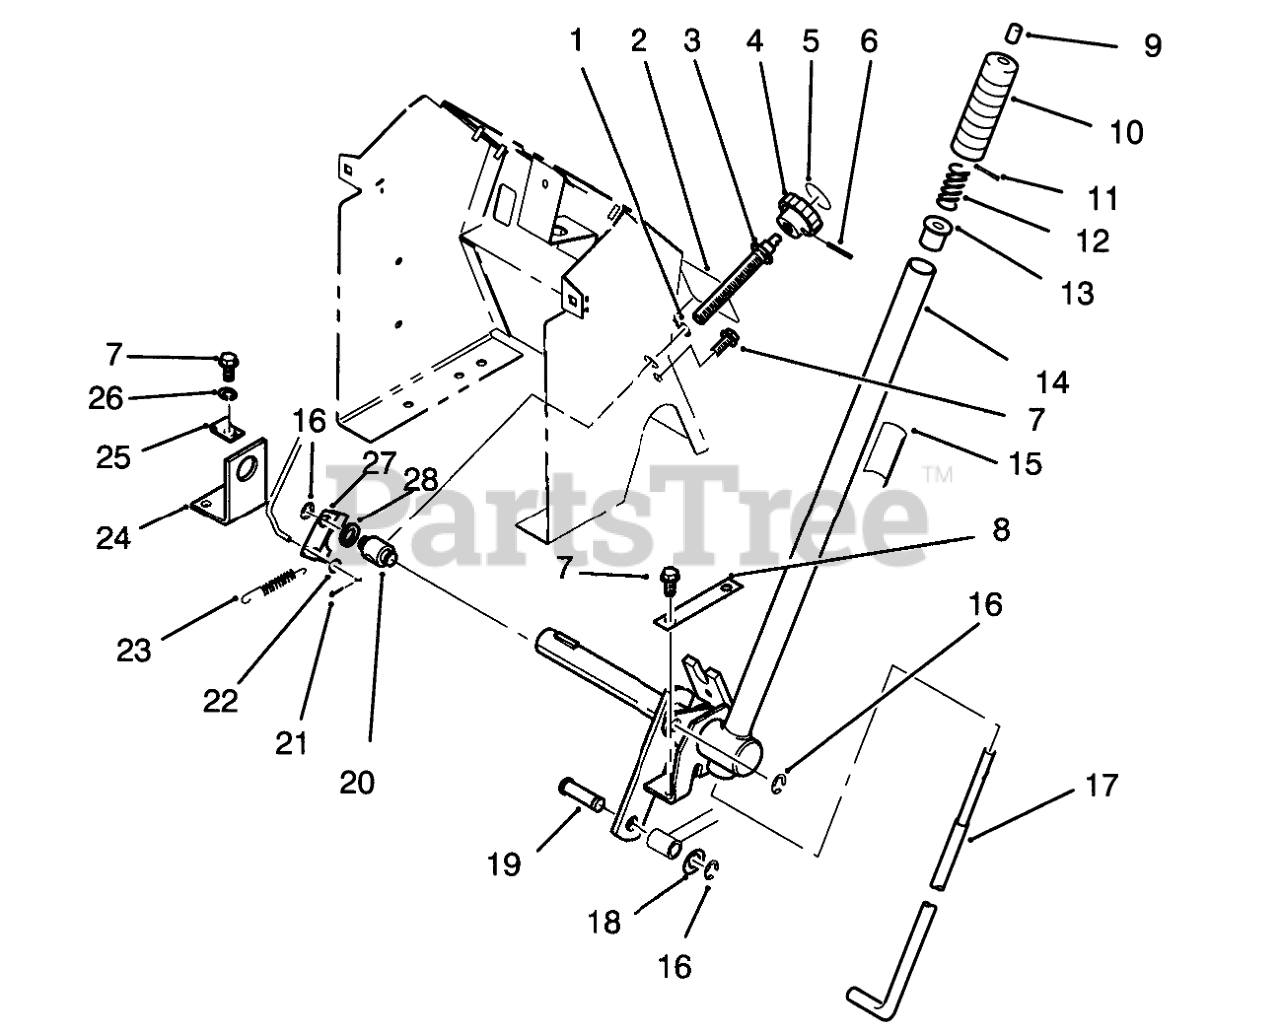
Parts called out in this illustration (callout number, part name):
1	Washer
2	Decal
3	ROD B
5	DECAL-HEIGHT KNOB
6	PIN-SPIROL
7	Screw
8	Plate
9	CAP-ROD, PLUNGER
10	HANDGRIP
11	PIN-SPIROL
12	SPRING-COMPRESSION
13	RETAINER-SPRING
14	WLDMT-LIFT HANDLE B
15	DECAL-LIFT
16	RING-RETAINING, EXTERNAL
17	ROD-LATCH LIFT
18	WASHER-FLAT
20	TRUNNION
21	Cotter Pin
22	WASHER-FLAT
23	SPRING-EXTENSION
24	BRACKET B
25	THROTTLE CONTROL CLP
26	Washer-Lock
27	PLATE B
28	Washer
